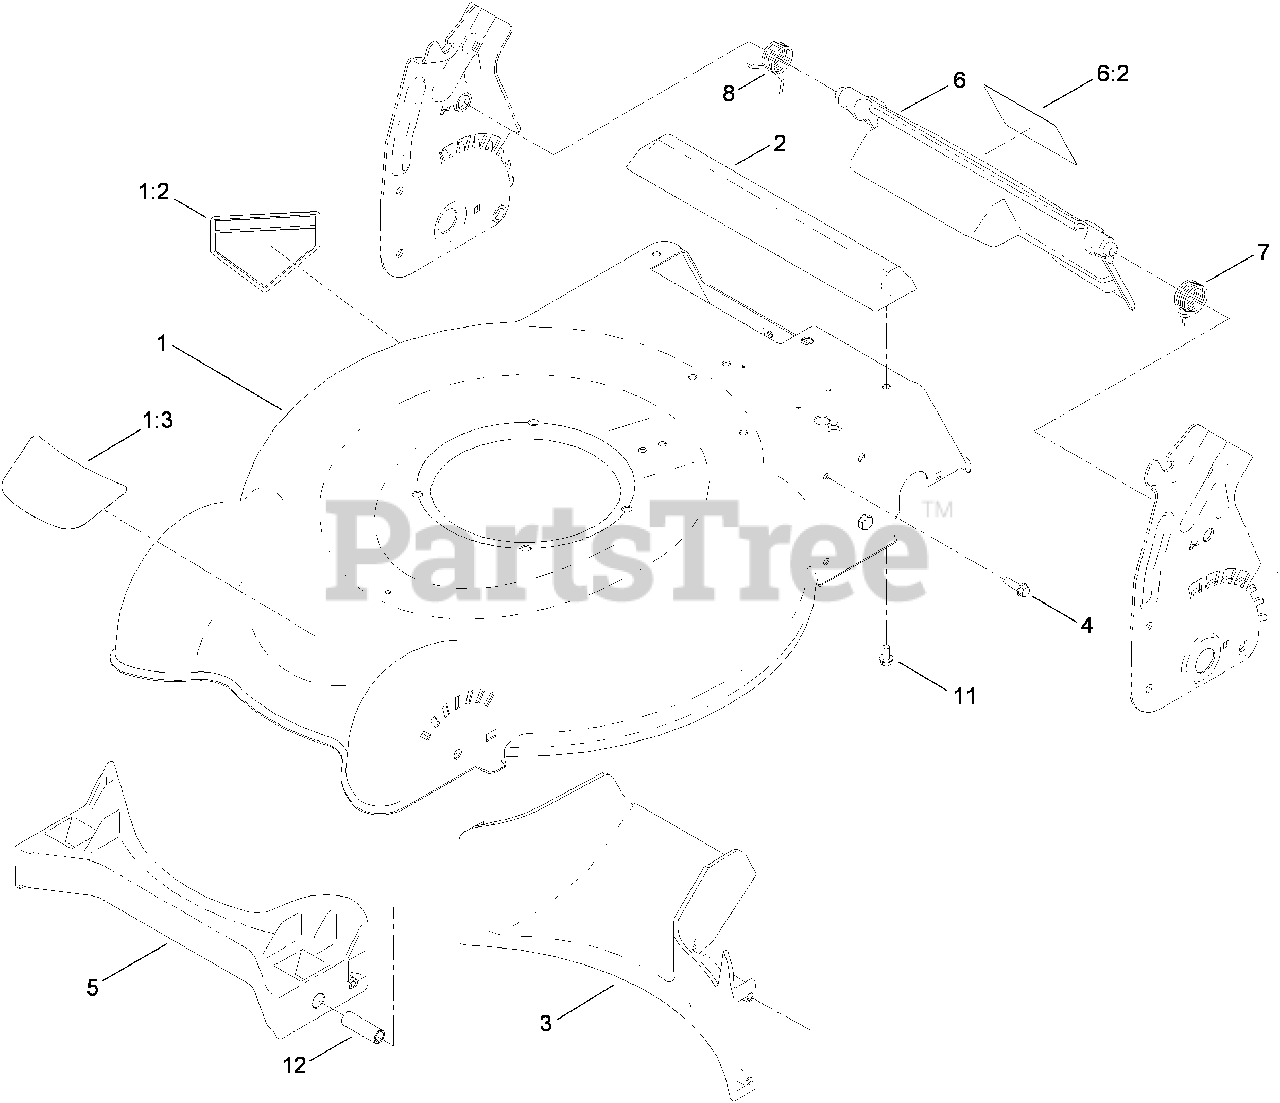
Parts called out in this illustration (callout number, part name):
1	HOUSING ASM
1:2	DECAL-DANGER
2	CHUTE-REAR
3	BAFFLE-REAR
4	SCREW-HWH
5	BAFFLE-FRONT
6	Rear Deflector ASM
6:2	DECAL-WARNING, CE
7	SPRING-TORSION, LH
8	SPRING-TORSION, RH
11	SCREW-PLASTITE
12	SPACER-BAFFLE, FRONT
